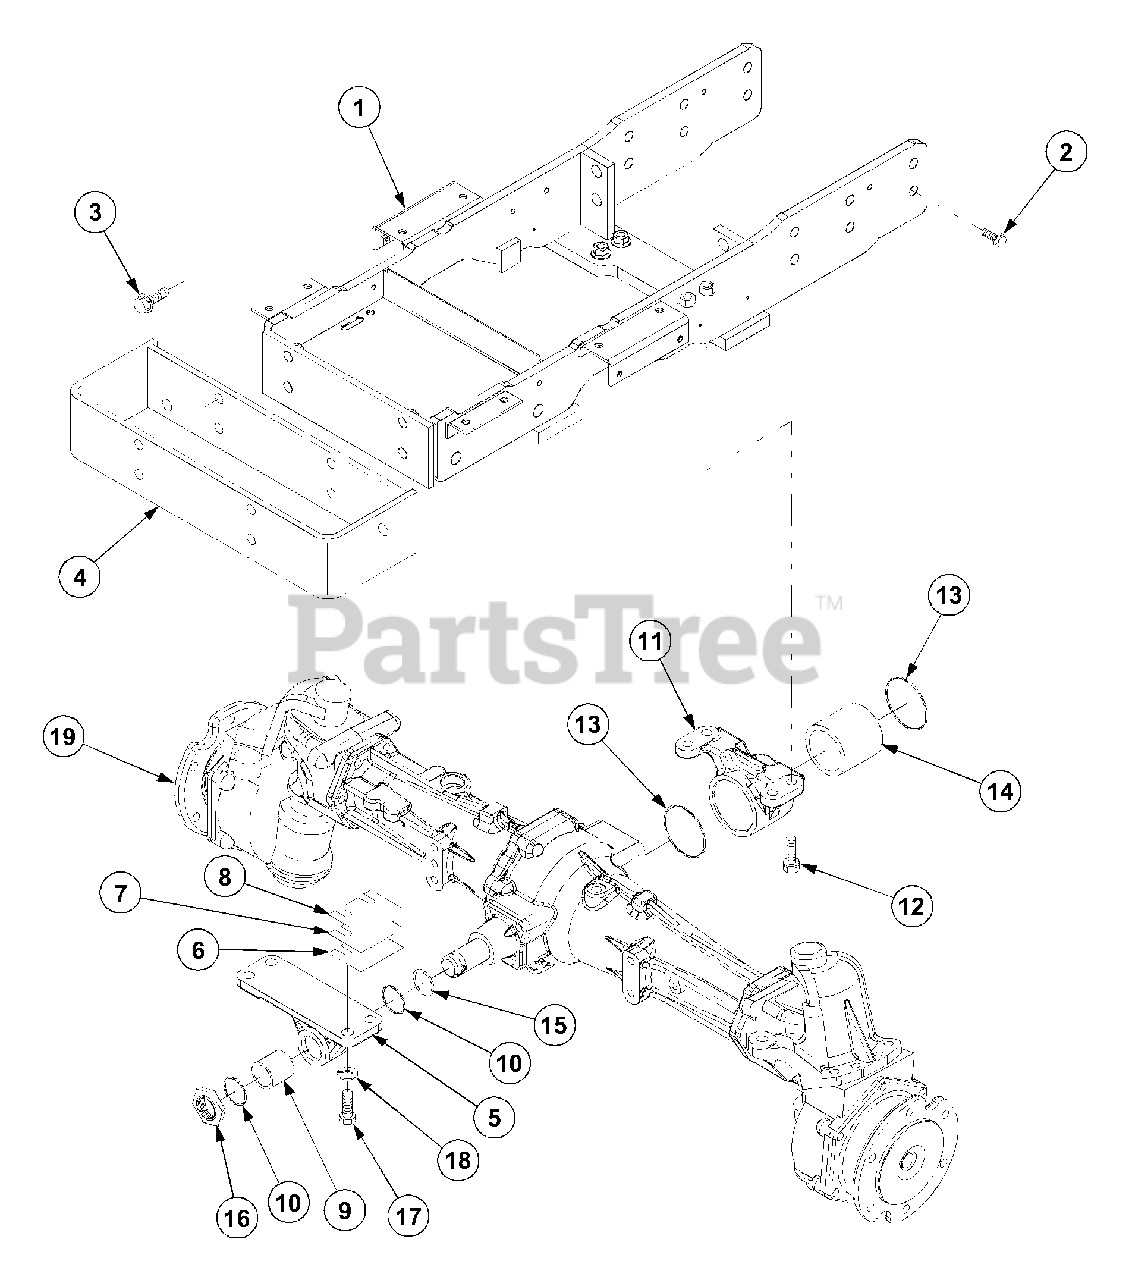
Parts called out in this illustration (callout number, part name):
1	Bracket,Front
3	Bolt,w/Washer
4	Bracket,Weight
5	Bracket,Front
12	Bolt,w/Washer
17	Bolt 7T
18	Washer,Spring
19	Front Axle Ass'y.
